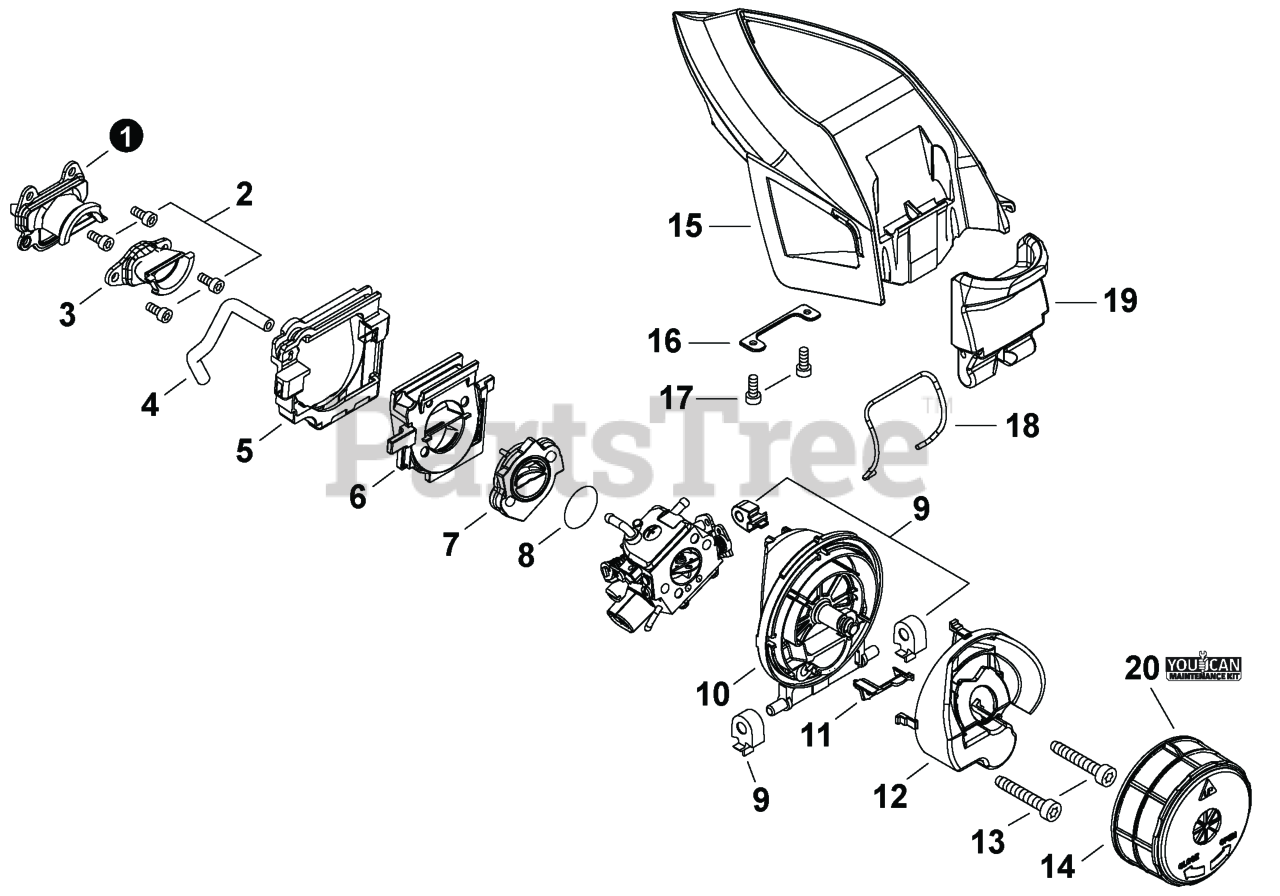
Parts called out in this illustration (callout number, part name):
1	BELLOWS, INTAKE
2	BOLT, TORX 4x12
3	BELLOWS, INTAKE
4	PIPE 3x6x90 MM
5	CUSHION
6	INSULATOR, INTAKE
7	INSULATOR, INTAKE
9	CUSHION
10	CASE, AIR FILTER
11	DUCT, AIR
12	DUCT, AIR
13	BOLT, TORX 5x55
14	FILTER, AIR
15	COVER, AIR FILTER
16	SPRING, FLAT
17	BOLT, TORX 4x12
18	RETAINER
19	LATCH, COVER
20	TUNE-UP KIT - YOUCAN™
